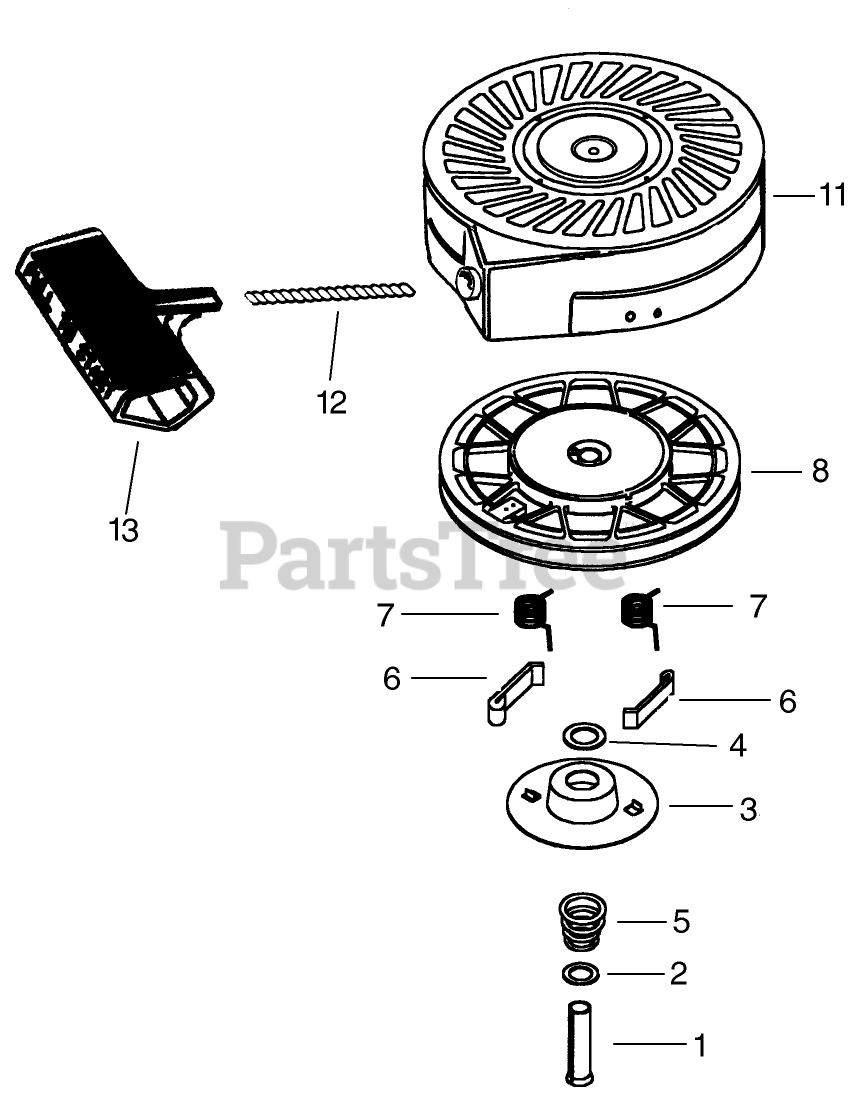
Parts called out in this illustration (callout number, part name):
1	Pin, Spring (Incl. Ref. #7)
2	Washer
3	Retainer
4	Washer
5	Spring-Brake
6	Dog-Starter
7	Spring-Dog
8	Pulley and Rewind Spring ASM
11	Starter Housing Assembly
12	Rope-Starter (98 cut to length)
13	Handle-Starter (STD)
